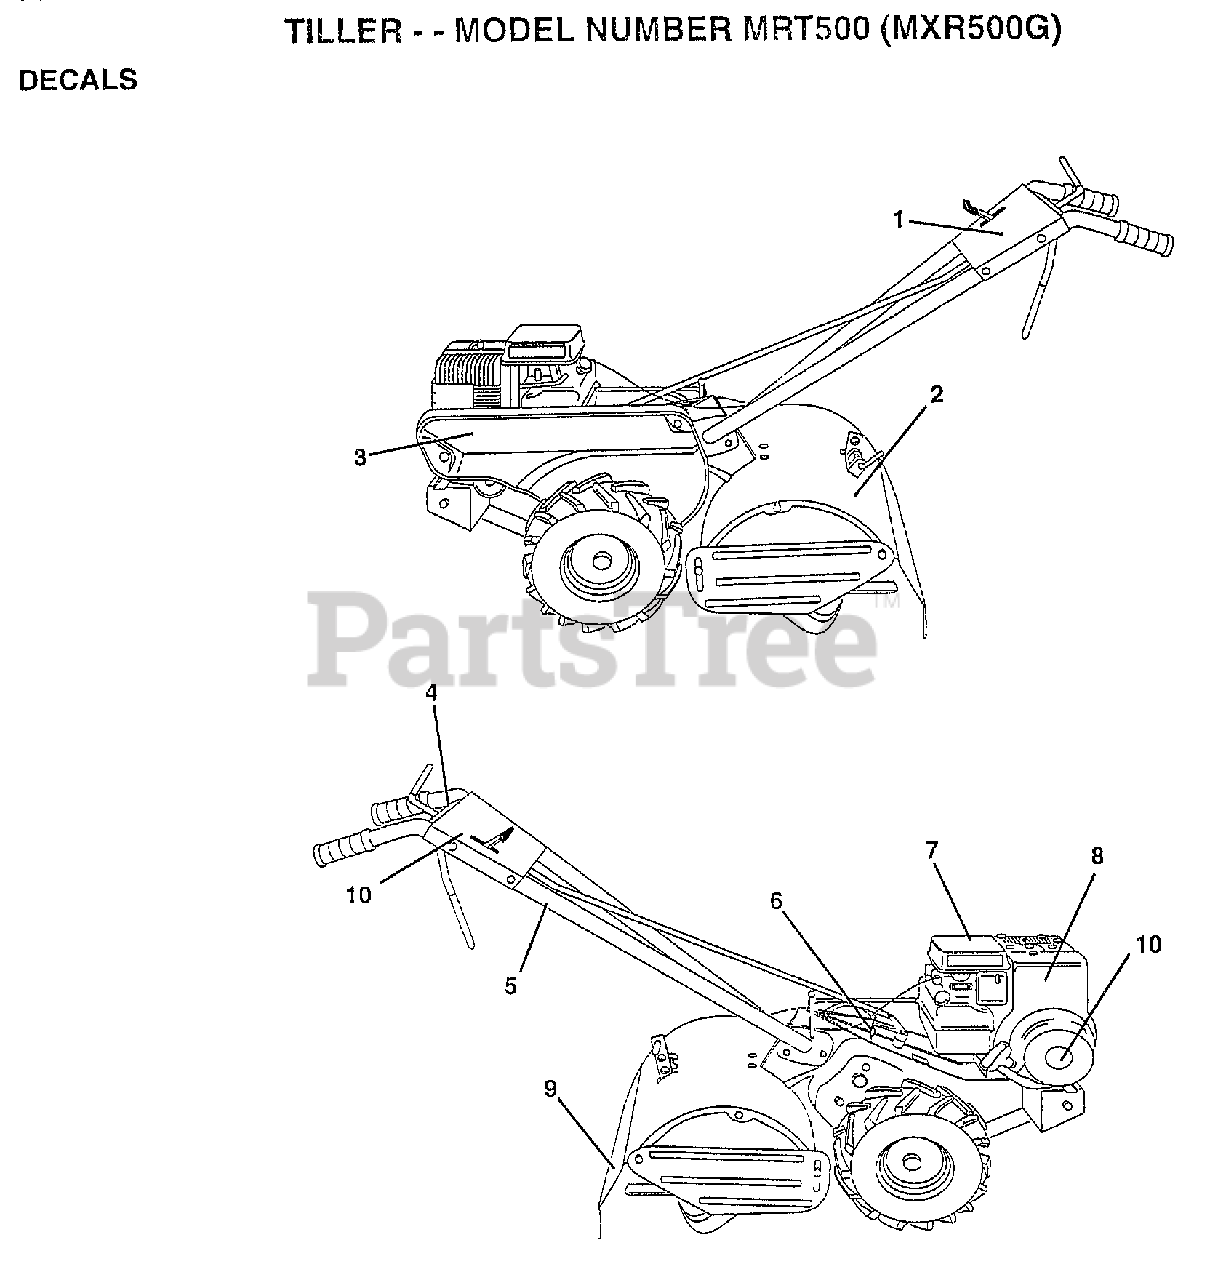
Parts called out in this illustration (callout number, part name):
1	DECAL CNTRL PANEL
2	DECAL SHIELD TINE
3	DECAL GUARD BELT
5	DECAL TI
7	DECAL TI
8	DECAL, BRIGGS & STRATTON
10	"DECAL CONTROL,PNL"
11	DECAL, 5 HP
